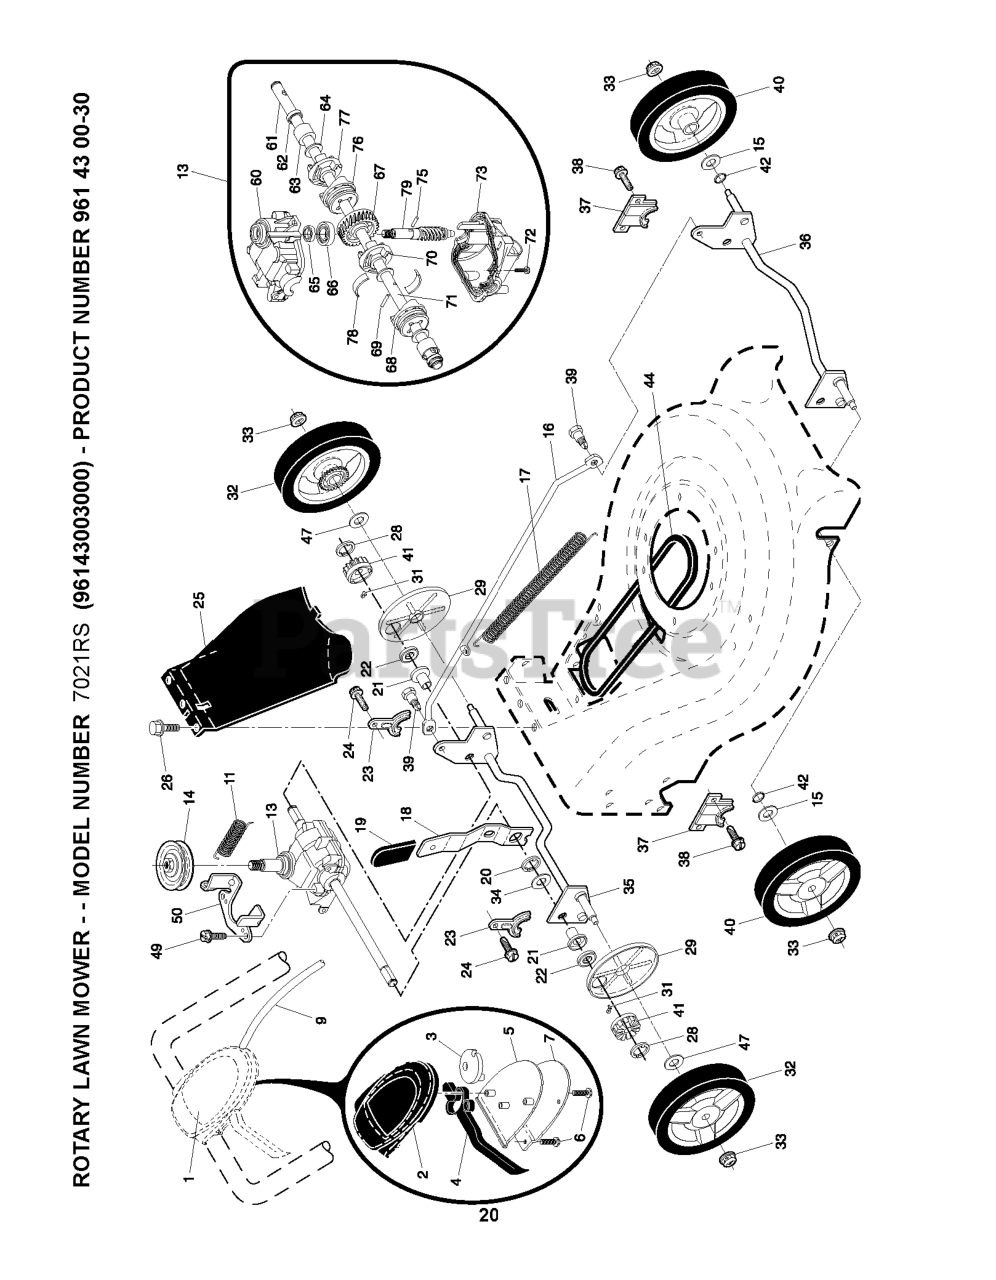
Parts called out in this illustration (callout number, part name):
1	DRIVE CONTROL ASSY, AUTO WALK
2	COVER TOP AUTO WALK CONTROL
3	PULLEY.CAM.DRIVE.CONTROL.EZ
4	LEVER, AUTOWALK DRIVE CONTROL
5	COVER BOTTOM AUTO WLK CONTROL
6	SCREW, PHILLIPS HEAD 10 X 5/8
7	BRACKET.DRIVE.CONTROL.MOUNT.BL
9	CABLE.ASSY.RGD.EZ.AUTO
13	TRANSMISSION.21.RWGD.AUTO.SP
14	PULLEY.1.PIECE
15	WASHER.FLAT.1/2
16	ROD.CONNECTING.SPT.BLACK
17	SPRING EXTENSION
18	SPRING.SELECTOR.SPT.21
19	KNOB, SELECTOR SPRING
21	BEARING SUPPORT
22	BEARING
23	BRACKET
25	COVER.DRIVE.21.RWGD.MO
28	E-RING 7/16 RE
29	COVER.DUST.WHEEL
31	PAWL, DRIVE
32	WHEEL & TIRE ASSY, REAR
33	NUT.HEX.FLANGE.3/8-16.LO(3 2)
35	SHAFT ASSY REAR
36	SHAFT ASSY, FRONT
37	RETAINER.FRONT.SHAFT
39	SHOULDER BOLT SEMI GIMLET PT.
40	WHEEL & TIRES ASSY, FRONT
41	PINIION.14.TOOTH.RGD
42	O-RING..070X.487.NEOPRENE
44	BELT.RGD.VS
47	WASHER FLUT
50	BELT KEEPER
60	CASE UPPER
61	SHAFT OUTPUT LONG
62	SEAL.OUTPUT.SHAFT
65	SEAL INPUT SHAFT
67	GEAR 28 TEETH
68	DOG.FIXED.LH.32003
69	PIN 7 33732
70	DOG.MOVEABLE.LH.32005
71	SHAFT OUTPUT SHORT (12294)
73	CASE, LOWER
75	PIN 3.50.337 - 33733
76	DOG.FIXED.RH.32004
77	DOG.MOVEABLE.RH.32006
78	SPRING LEAF
79	SHAFT WORM
